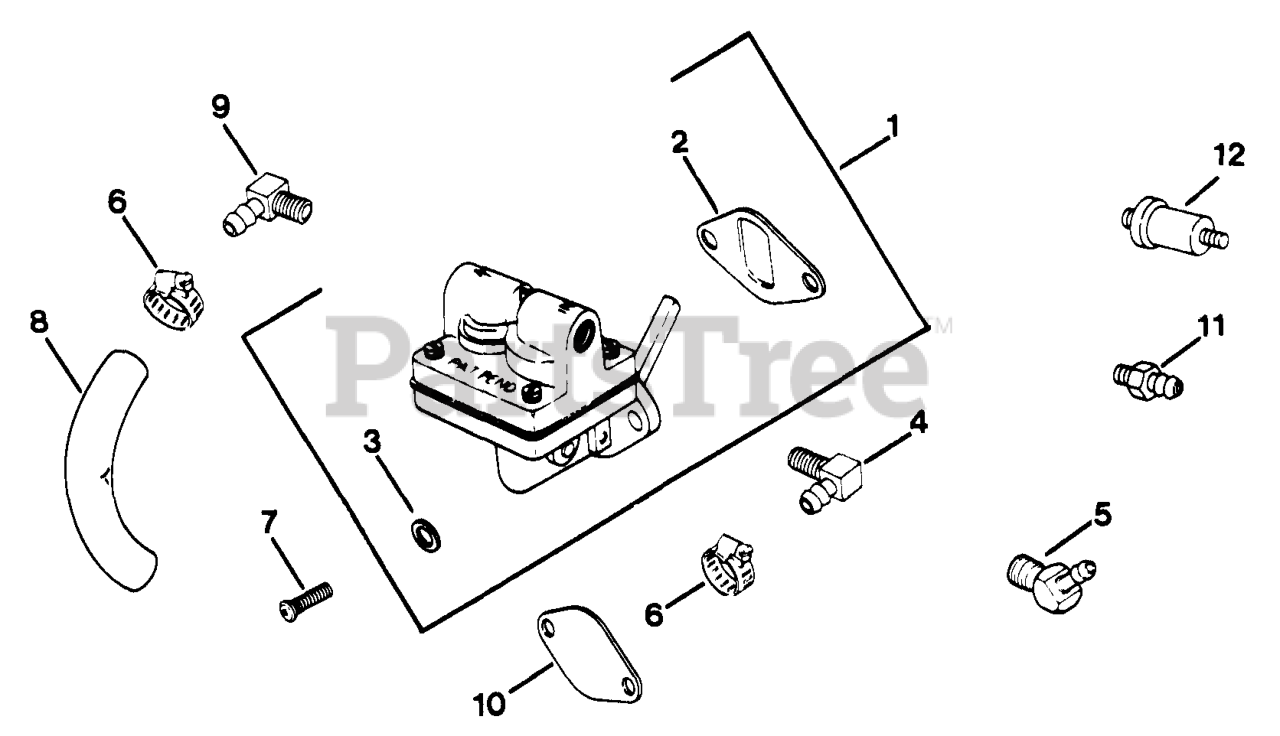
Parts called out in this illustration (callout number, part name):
2	GASKET - USE 25 041 09
3	WASHER, FLAT 1/4" (O.D. 1/2")
4	CONNECTOR, 90 DEG. HOSE
5	CONNECTOR, 45 DEG.
6	CLAMP, HOSE 1/2" USE 25 237 14-S
7	SCREW, SEMS 1/4-20X3/4"
8	LINE - DISCONTINUED
